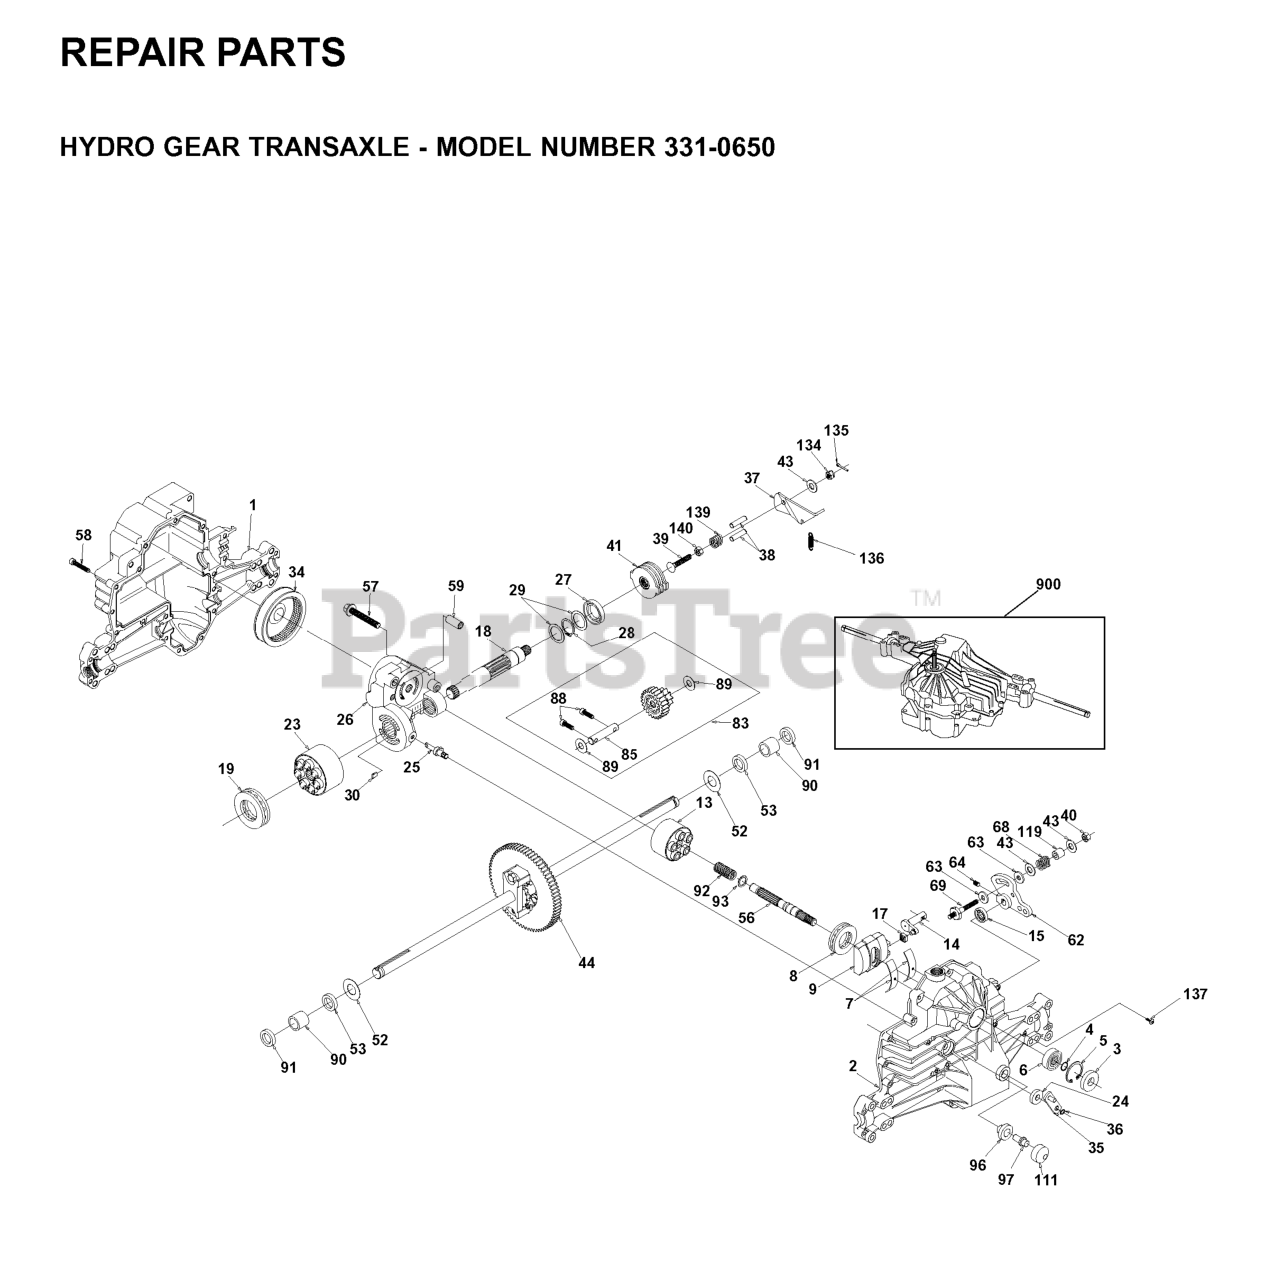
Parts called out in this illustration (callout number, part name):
1	LOWER HOUSING
3	SEAL.LIP.H-G.(9008000-0128)
4	RING RETAINING 2003016
5	RING.RETAINING.(2003052)
6	BALL BEARING
7	CRADLE BEARING
8	BEARING, THRUST 50551
9	SWASHPLATE (2003087)
17	SLOT GUIDE
18	SHAFT, MOTOR
19	BEARING, THRUST 50552
23	BLOCK, CYL ASSY
25	BYPASS ACTUATOR
26	CENTER SECTION 70250
28	RETAINING RING
34	ELEMENT, OIL FILTER
35	BYPASS ARM
36	RETAINING RING 44870
38	ACTUATING PIN 44891
39	BOLT 5/16-24 X 1-3/4
40	LOCKNUT, HEX 5/16-24
41	BRAKE ROTOR 70135 HYDRO-GEAR
43	WASHER .34X.88X.06.44130
44	KIT SVC DIFFRENTIAL 70130
52	WASHER.HYDRO-GEAR 44875
53	SEAL.HYDRO.53901
56	SHAFT.INPUT.50005
58	BOLT #44876
62	CONTROL ARM 50254
63	DAMPENER PUCK
64	SCREW.SET.50018
68	SPRING HELICAL COMP 50277
89	WASHER 50132
90	SLEEVE.BEARING 50118
91	SEAL LIP.75X1X.158 50941
92	SPRING 2003014
119	SPACER.HYDRO GEAR 50278
134	CASTLE NUT
135	PIN.COTTER.44101.
139	SPRING, COMPRESSION 50431
140	NUT, HEX 5/16-24
900	TRANSMISSION
